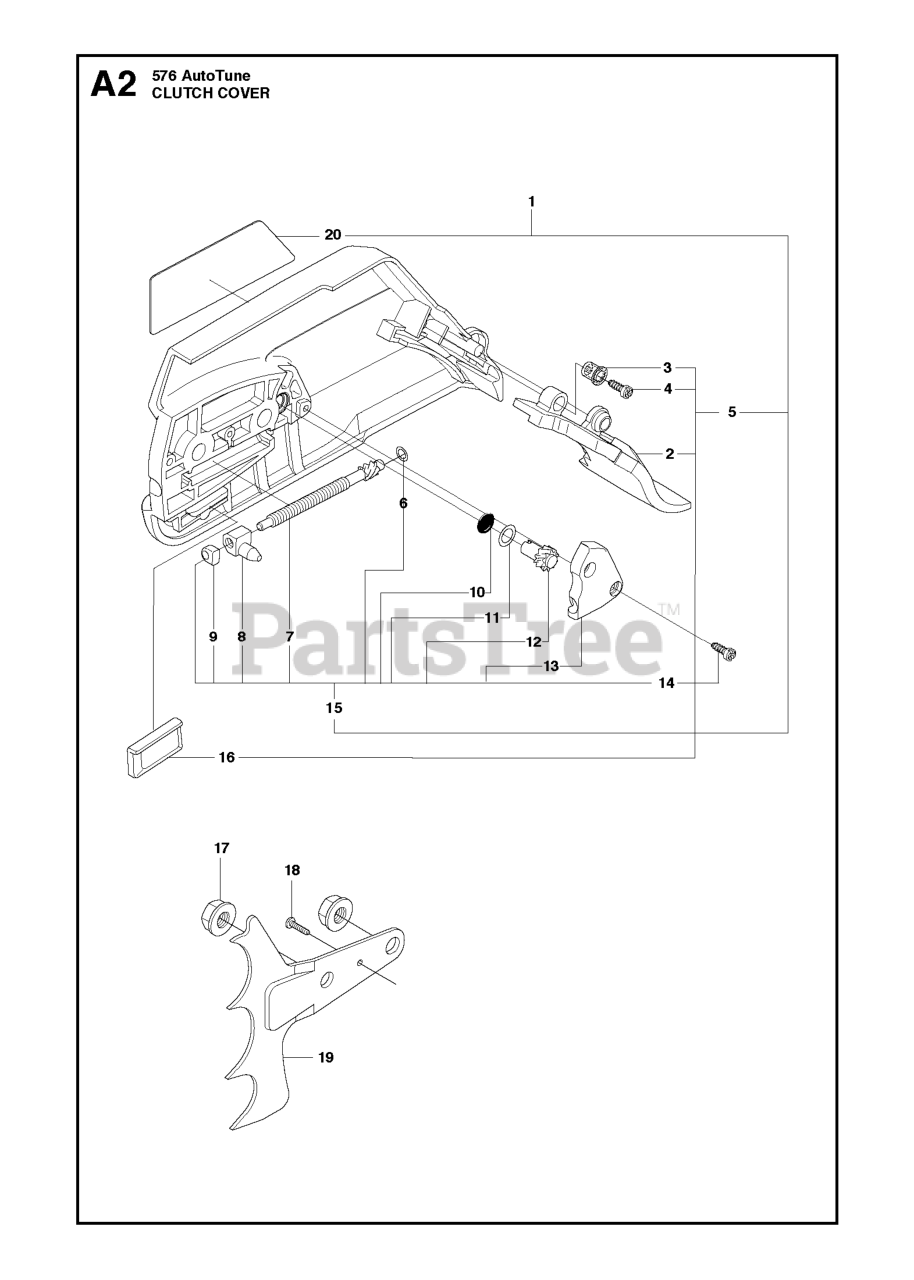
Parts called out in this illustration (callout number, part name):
1	CLUTCH COVER ASSY
5	CLUTCH COVER ASSY H SILVER R-
7	WORM SCREW / ADJUSTER
12	WORM WHEEL
15	KIT-CHAIN TENSIONER
16	CHAIN GUIDE
17	NUT M8 FLANGE
19	SPIKE OUTER
